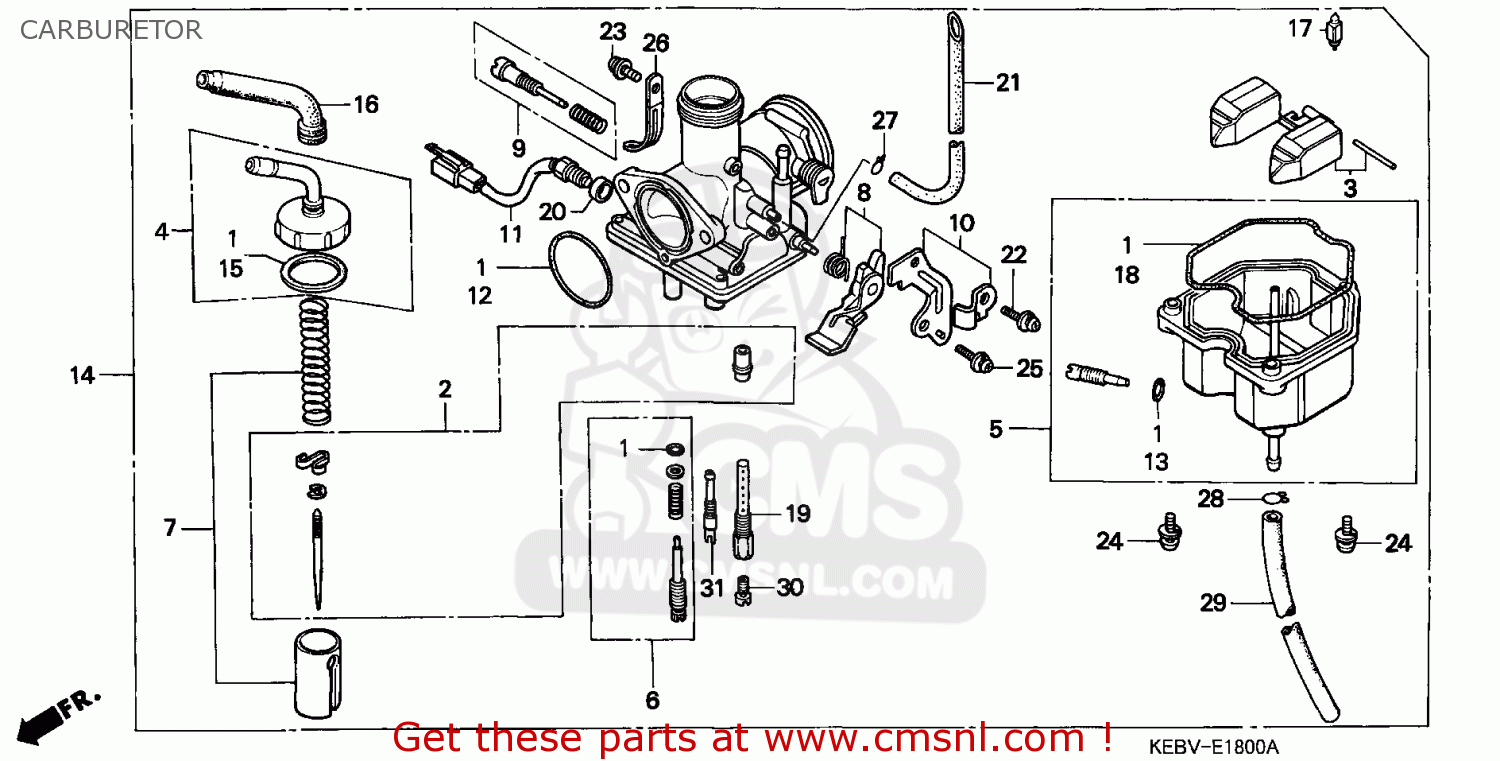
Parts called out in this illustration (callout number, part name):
1	GASKET SET
2	NEEDLE SET,JET
3	FLOAT SET
4	TOP SET
5	CHAMBER SET,FLOAT
6	SCREW SET,A
7	VALVE SET,THROTT.
8	LEVER SET,CHOKE
9	SCREW SET,B
10	PLATE SET,STAY
12	O-RING,2.4X29
13	O-RING,1.3X4.3
14	CARBURETOR ASSY
15	GASKET,TOP
16	CAP,CABLE SEALING
17	VALVE,FLOAT
18	GASKET,FLOAT CHAM
19	HOLDER,NEEDLE JET
21	TUBE
22	SCREW-WASHER 4X8
24	SCREW-WASHER,4X16
25	SCREW-WASHER,5X12
27	CLIP B1 8,TUBE
28	CLIP B1 6.5 TUBE
29	TUB,3.5X400
30	JET,#95
31	JET COMP,SLOW
